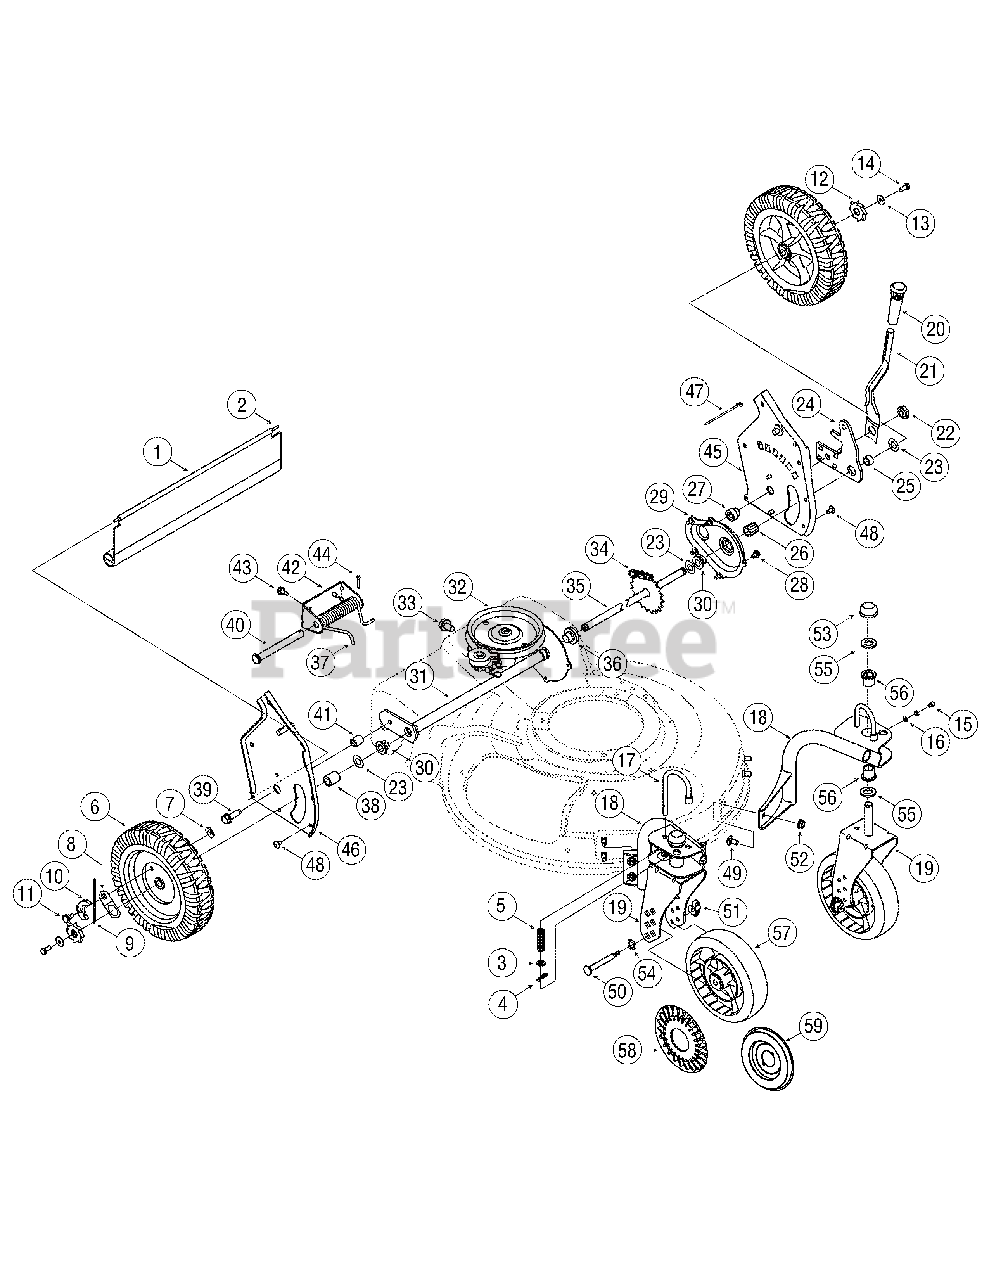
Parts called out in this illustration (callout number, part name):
1	Trail Shield
2	Trail Shield Wire
3	Flat Washer.330 ID x.630 OD
4	Cotter Pin
5	Compression Spring
6	Wheel 9 x 2
7	Top Lock Tab Weld Nut 1/4-20
8	Ratchet Pawl Plate
9	Plastic Spring Ratchet
10	Pawl LH
11	Shoulder Screw.340 ID x.285 OD
12	Wheel Ratchet
13	Bell Washer.265 ID x.75 OD
14	Hex Cap Screw 1/4-20 x.620
15	Grease Fitting
16	Flat Washer.203 ID x.403 OD
17	Wheel Pin Lock
21	Spring Lever
22	Shoulder Nut.825 x .165 Lg.
23	Flat Washer .508 ID x 1.0 OD
25	Spacer .510 ID x .70 OD
26	Sleeve Bearing .504 ID x .830 OD
27	Shoulder Spacer
28	Tap Screw 1/4-20 x .375
32	Transmission Assembly Complete
33	Hex Screw 5/16-18
34	Chain
35	Rear Axle Assembly
36	Flange Bearing .506 ID x .715 Lg
37	Torsion Spring
38	Spacer .550 ID x .750 OD
39	Screw 3/8-16 x .25
40	Clevis Pin .50 Dia x 4.82 Lg.
41	Spacer .385 ID x .624 OD
44	Cotter Pin
48	Screw 1/4-14 x.500
49	Carriage Bolt 5/16-18 x.62
50	Caster Axle
51	Wing Nut
52	Flange Lock Nut 5/16-18
54	Wave Washer.531 ID x.781 OD
55	Flat Washer.640 ID x 1.12 OD
56	Flange Bearing
57	Wheel 7 x 2
58	Hubcap - Spoke w/ Hole
59	Hubcap - Radial Spoke
